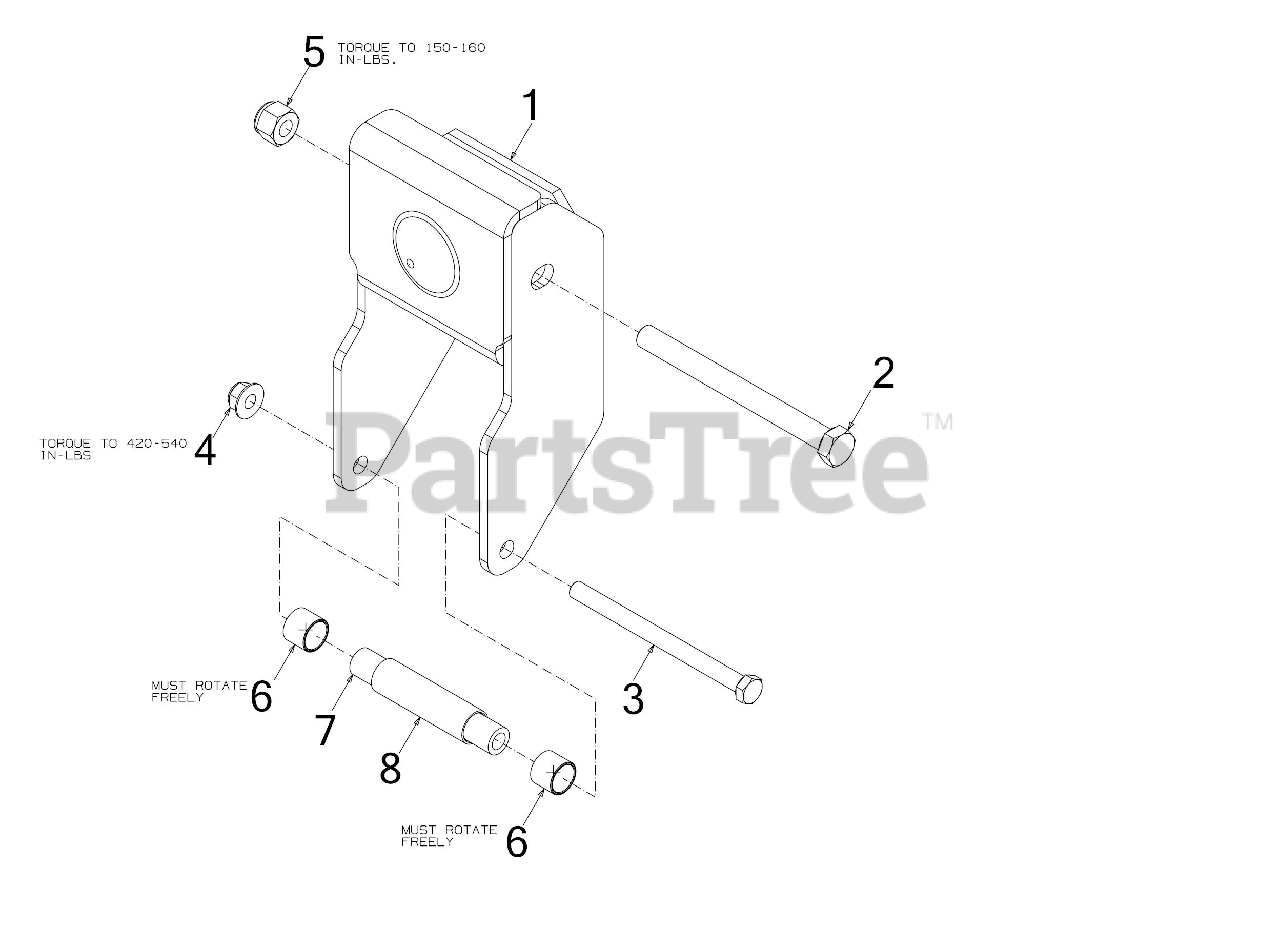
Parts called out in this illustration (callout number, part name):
1	PUSH BRACKET ASSEMBLY
2	SCREW 1/2-20 x 5.50 GR5
3	SCREW 3/8-16X5.0 GR5
5	HEX NUT CENTER
6	SLEEVE BEARING
7	SPACER-.385 x .625 x 4.07
8	SPACER-5/8 ID x 2.
